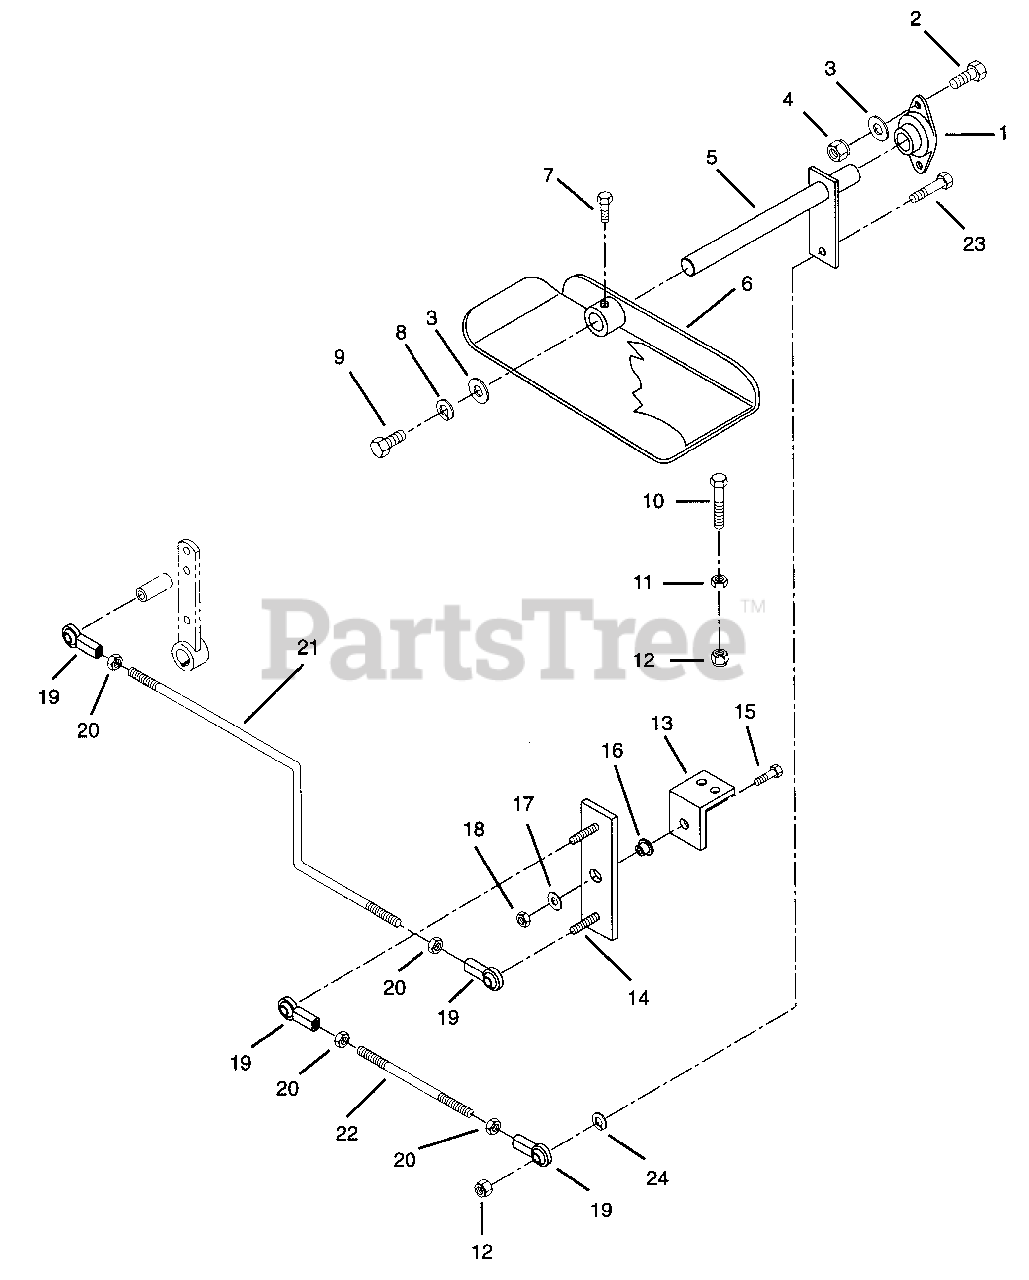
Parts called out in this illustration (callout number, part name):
1	Bearing-Flange .75 x 2 Hole x 2.123
2	Bolt-Hex .38-16 x .75 Grade 5
3	Washer-Flat-Steel .406 x .812 x .065
4	Nut-Locking-Nylon .375-16 Grade 2
5	Weldment,Control
6	Weldment,Foot Control Lever
7	Bolt-Hex .25-28 x .50
8	Washer-Lock .375 x .094
9	Bolt-Hex .38-16 x 1.00 Grade 5
10	Bolt-Hex .31-18 x 3.50 Grade 2
11	Nut-Hex .312-18 Grade 2
12	Nut-Locking-Nylon .312-18 Grade 2
13	Bracket,Reverse Pivot Mount
14	Weldment,Reverse Pivot Bracket
15	Bolt-Hex .31-18 x 1.75 Grade 5
16	Bushing-Flange .344 x .468 x .485 x .750
17	Washer-Flat-Steel .344 x .688 x .065
18	Bolt-Hex .31-18 x 1.75 Grade 5
19	RodEnd, 5/16" Femate
20	Nut-Jam .312-24
21	Rod,Direction Control Rear
22	Rod,Direction Control Short
23	Bolt-Hex .31-18 x 1.25 Grade 5
24	Washer-Lock .313 x .078
